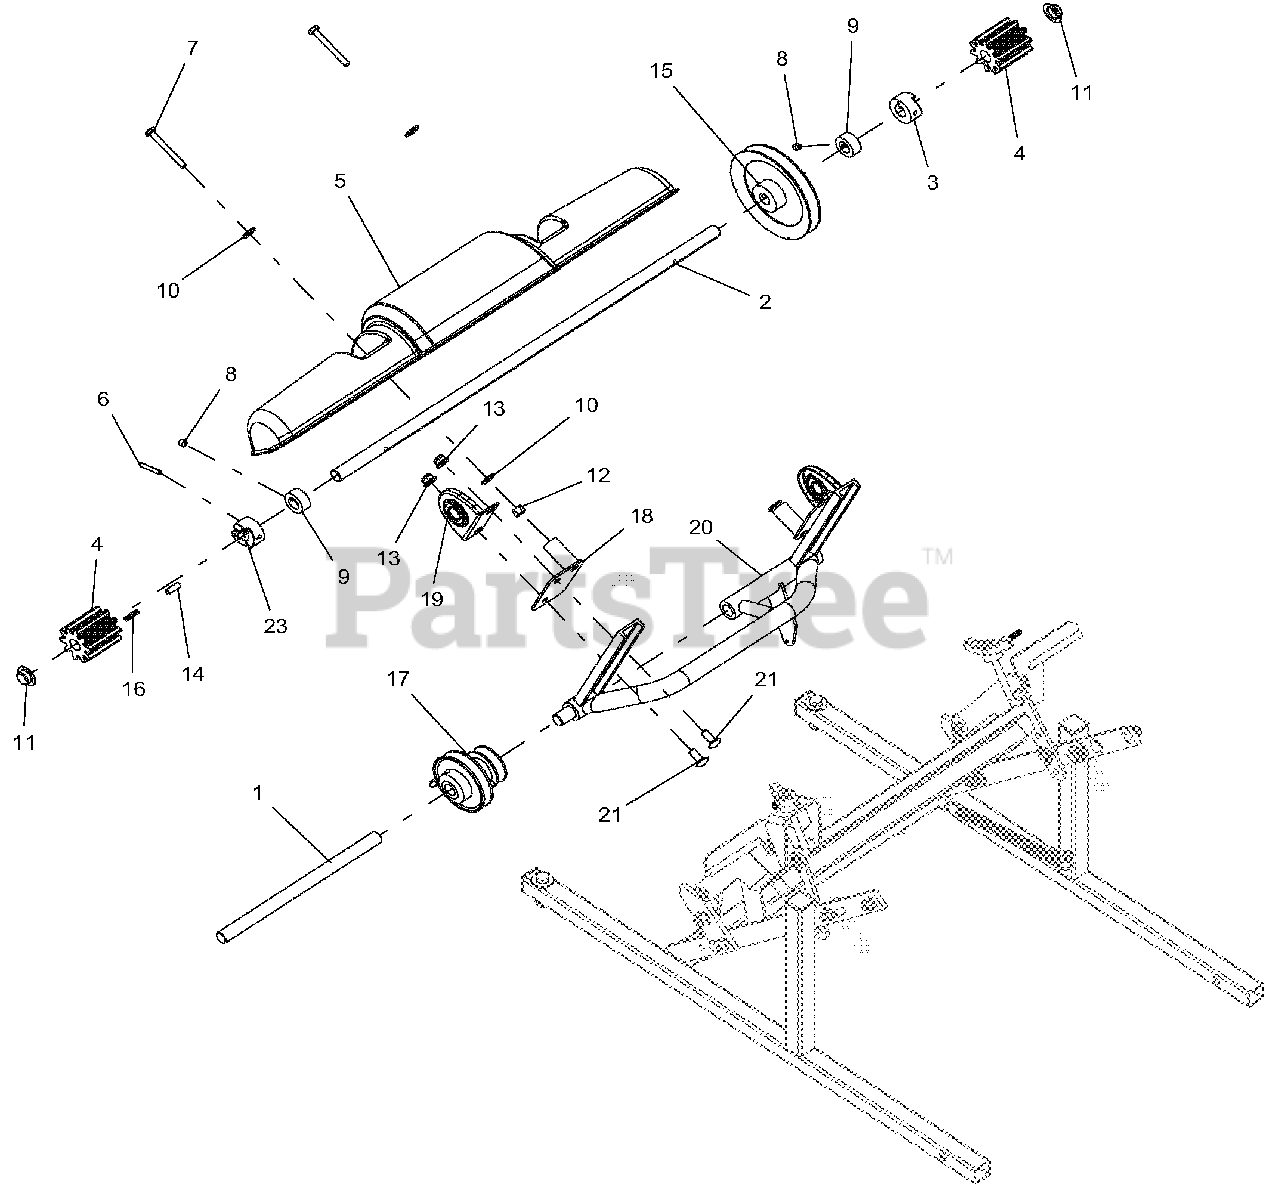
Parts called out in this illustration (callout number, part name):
1	SHAFT, PIVOT LONG
2	SHAFT, WHEEL DRIVE
3	CLUTCH, RIGHT SP
4	GEAR, DRIVE (SP)
5	COVER, PLASTIC -SP (HIGH WHEEL)
6	PIN-ROLL .188X1.25
7	BLT-HEX .25-20X2.25 GR5 YWZC
8	SET SCREW 5/16-18 X 5/16 CP
9	SET COLLAR .625ID X .50
10	WSHR-FL-STL.312X.734X.065 YWZ
11	NUT, PUSH .625 DIA. PAL
12	NUT-LK-NYL .250-20 YWZC
13	NUT-LK-NYL-FLG .31-18 YWZC
14	DOWEL PIN 1/4 X 3/4
15	PULLEY, 5" OD X 5/8" ID
16	SPRG, COMPRESSION
17	WMT,DBL SP IVP PULLEY 17344K
18	WLDMT, SP BELT COVER MOUNTING (BLACK)
19	BEARING ASSY, SP TOPSHAFT, HWM
20	WMT-SELF PROPEL FRAME (BLACK)
21	BLT-RHDSSQNK .31-18X.75 G5YZ
23	CLUTCH, LEFT SP
